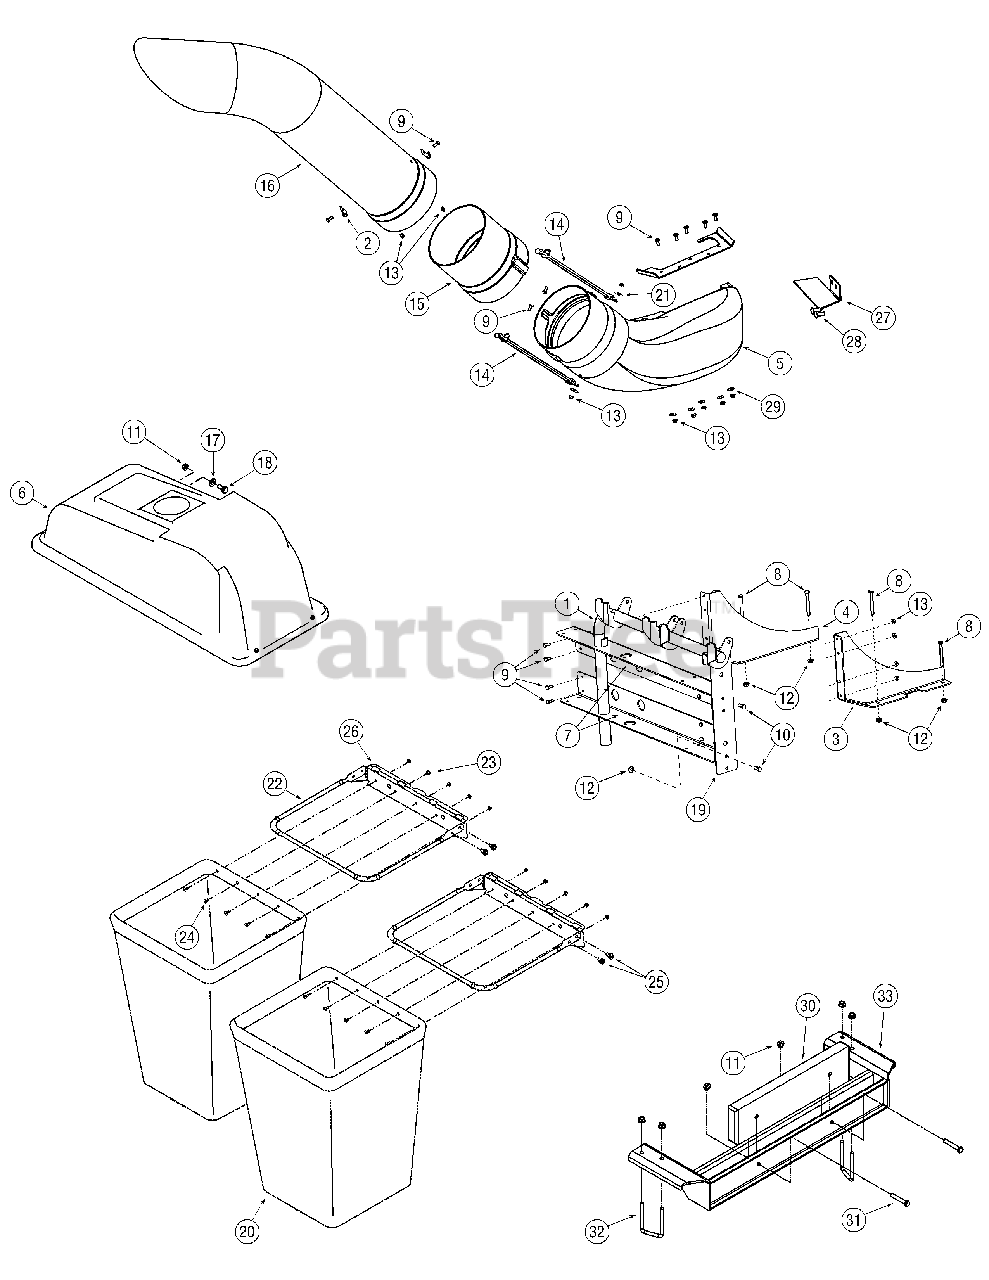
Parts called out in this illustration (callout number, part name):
2	Retainer Hook Bracket
5	Elbow Chute Assembly
6	Grass Catcher Cover
8	Hex Bolt 5/16-18 x 2.75"
9	Hex Bolt 1/4-20 x .620"
10	Hex Bolt 5/16-18 x .75"
11	Flange Lock Nut 3/8-16
12	Flange Lock Nut 5/16-18
13	Hex Flange Lock Nut 1/4-20
14	Retainer Strap Assembly
15	8" Extension Chute
16	8" Catcher Tube
17	Belleville Washer
18	Shoulder Screw 3/8-16
20	Grass Bag
21	Flat Washer
25	Machine Screw
28	Carriage Bolt 3/8-16
29	Bell Washer
30	Weight Bar
31	Hex Head Screw 3/8-16
32	U-bolt 3/8-16
